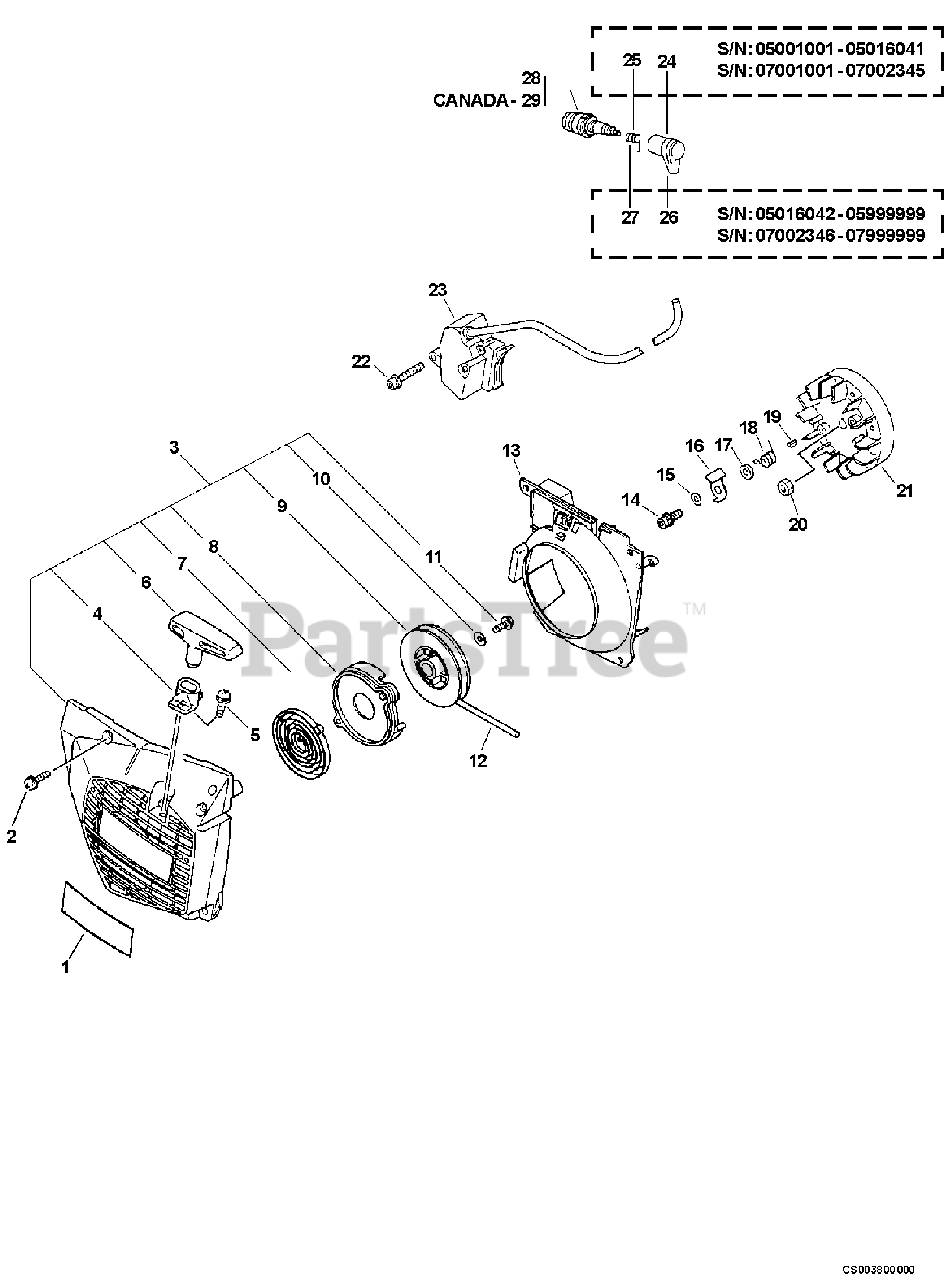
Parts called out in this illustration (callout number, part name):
2	SCREW 5×18
3	STARTER ASSY
4	GUIDE, ROPE
5	SCREW 3×14
6	GRIP, STARTER
7	SPRING, RECOIL
8	PLATE, STARTER
9	REEL, ROPE
10	WASHER 5.2×16×1.0
11	SCREW 5×12
12	ROPE, STARTER
13	COVER, FAN
14	BOLT 5×14
15	WASHER 5.5×12×0.8
16	PAWL, STARTER
17	SPACER 5.2×8×2.1
18	SPRING, TORSION
19	KEY, WOODRUFF
20	NUT, FLANGE M8
21	FLYWHEEL
22	BOLT 4×30
23	COIL, IGNITION
24	CAP, SPARK PLUG
25	TERMINAL, SPARK PLUG
26	CAP, SPARK PLUG
27	TERMINAL, SPARK PLUG
28	SPARK PLUG - BPM7A
29	SPARK PLUG - BPMR8Y
